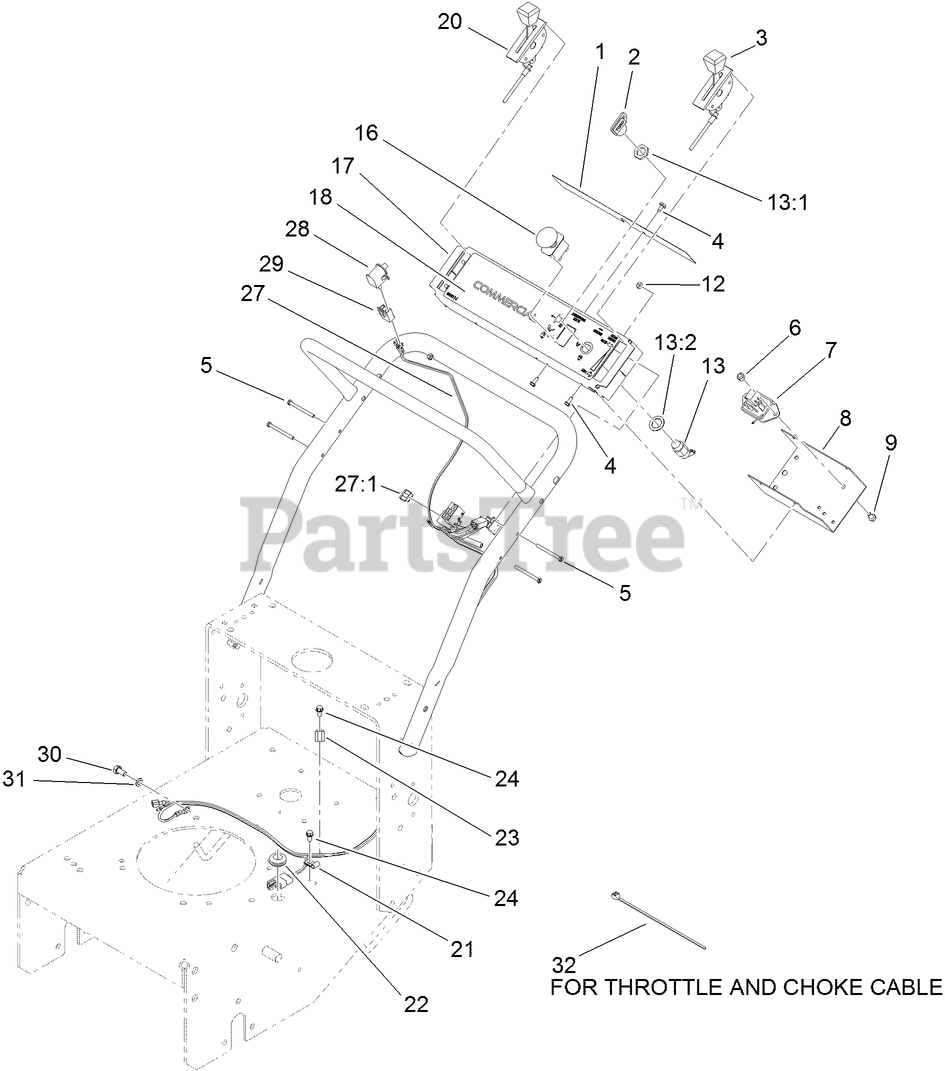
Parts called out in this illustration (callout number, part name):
1	DECAL-DANGER
2	KEY-IGNITION
3	CABLE-THROTTLE
4	SCREW-HWHTF
5	SCREW-SHH
6	NUT-LOCK, NI
7	MODULE-DELAY
8	PANEL-BOTTOM
9	SCREW-HH
12	NUT-LOCK, NI
13	SWITCH-ON / OFF
13:1	NUT-HH
13:2	WASHER-TOOTH, INTERNAL
16	SWITCH-PTO
17	PANEL-CONTROL
18	DECAL-PANEL, CONTROL
20	CABLE-CHOKE
21	CLIP-CLOSED, INSULATED
22	GROMMET
23	CLAMP-R
24	SCREW-HWH
27	HARNESS-WIRE
27:1	FUSE-BLADE, 7.5 AMP
28	SWITCH-BAIL
29	CONNECTOR-BODY
30	SCREW-HH
31	WASHER-LOCK
32	TIE-CABLE
